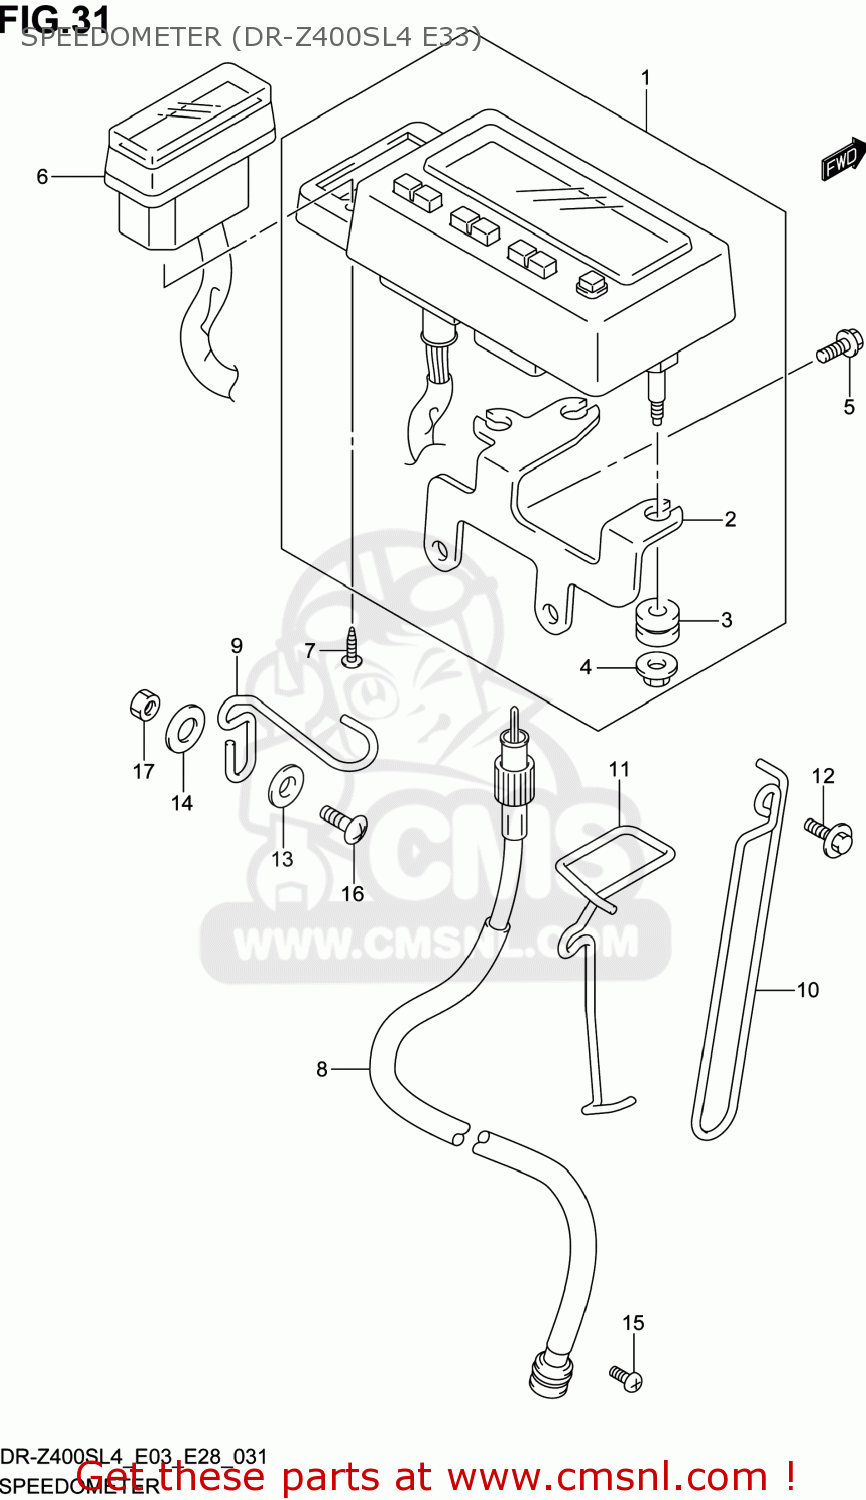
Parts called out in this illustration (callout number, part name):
1	SPEEDOMETER ASSY
2	BRACKET
3	CUSHION,METER
4	NUT
5	BOLT
6	BOX ASSY,PILOT LAMP
7	SCREW
8	CABLE ASSY,SPEEDOMETER
9	GUIDE,SPEEDOMETER CABLE
10	GUIDE,METER CABLE NO.2
11	GUIDE,SPEEDOMETER CABLE NO.3
12	BOLT(6X20)
13	WASHER(6.5X18X1.6)
14	WASHER
15	SCREW
16	SCREW
17	NUT
